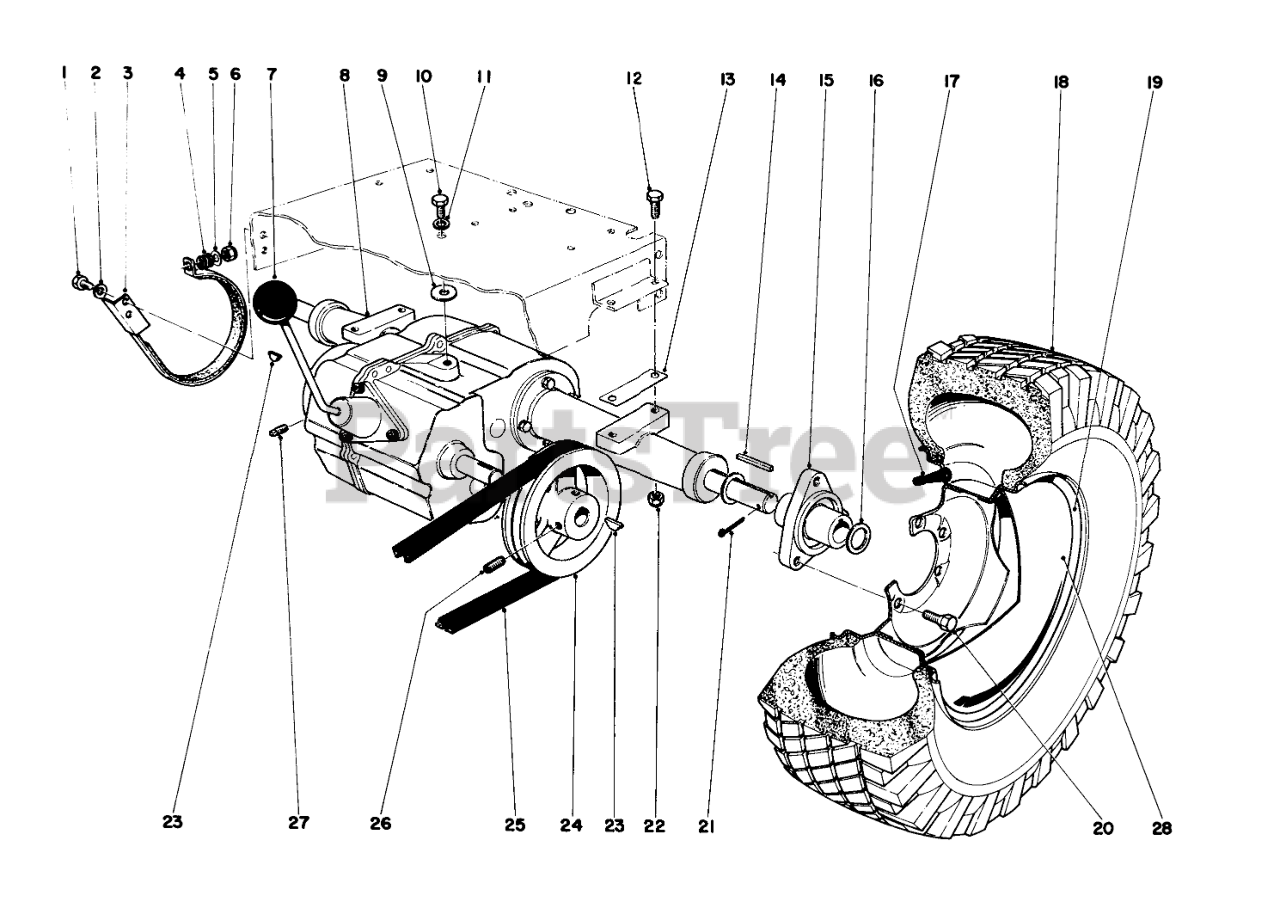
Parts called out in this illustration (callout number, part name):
1	SCREW-HH
2	WASHER-LOCK
3	Brake Band Assy.
4	Spring
5	WASHER-FLAT
6	Nut
8	Transmission Complete
9	WASHER-FLAT
10	SCREW-HH
11	WASHER-LOCK
12	SCREW-HH
13	Axle Pad
14	KEY-SQUARE
15	Wheel Hub
16	Washer
17	STEM-VALVE
18	Tire
19	Rear Wheel
20	Tapered Capscrew
21	PIN-COTTER
23	KEY-WOODRUFF
24	Pulley Transmission
25	V-BELT, TRANS (SET OF 2)
26	SCREW-SET
27	SCREW-SET
28	Hub Cap 960
